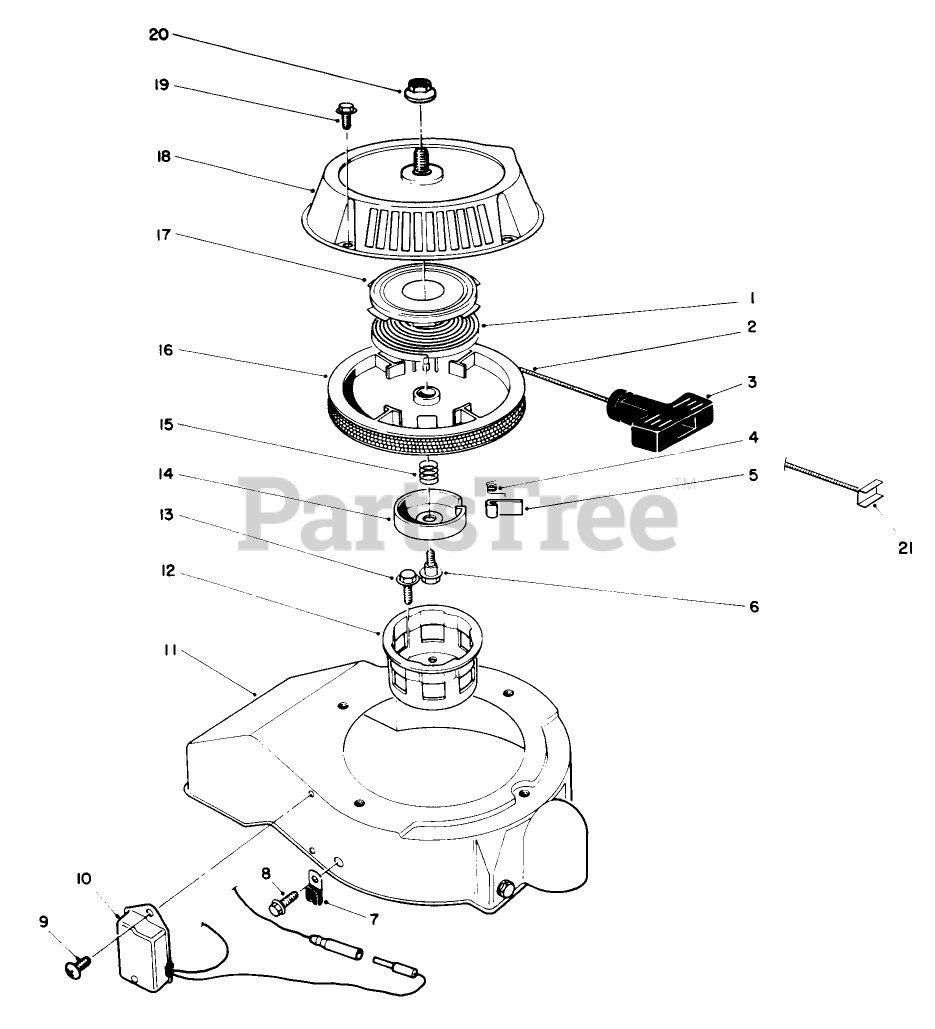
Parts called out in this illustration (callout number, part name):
1	SPRING
3	HANDLE-RECOIL
4	SPRING
9	SCREW
11	SHROUD
12	CUP - STARTER
14	RETAINER
15	SPRING
17	Retainer-Recoil Spring
19	MOUNTING SCREW
